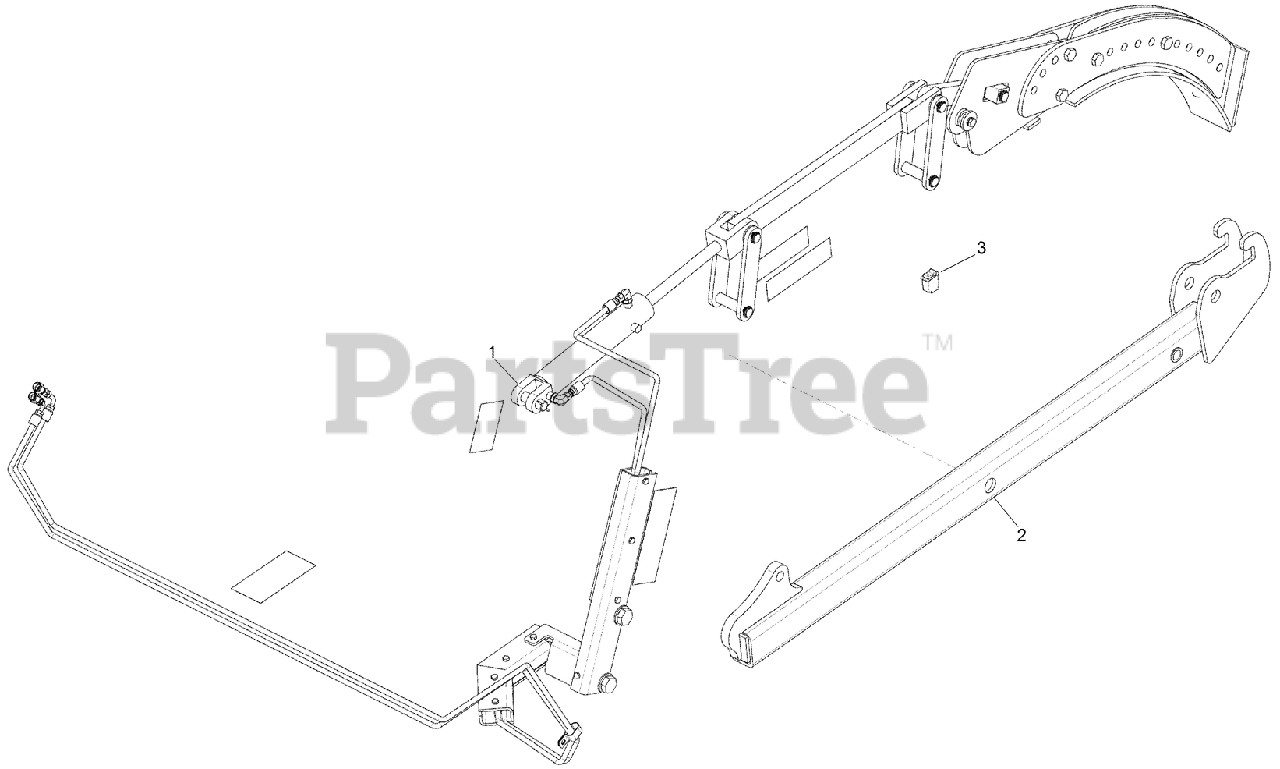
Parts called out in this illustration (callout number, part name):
1	KIT - Hydraulic Crumber
2	WELDMENT - Tube, Crumber
3	SWITCH-ROCKER, 2 POLE
5	BLADE - Hydraulic Crumber, 8 Wide Cut
